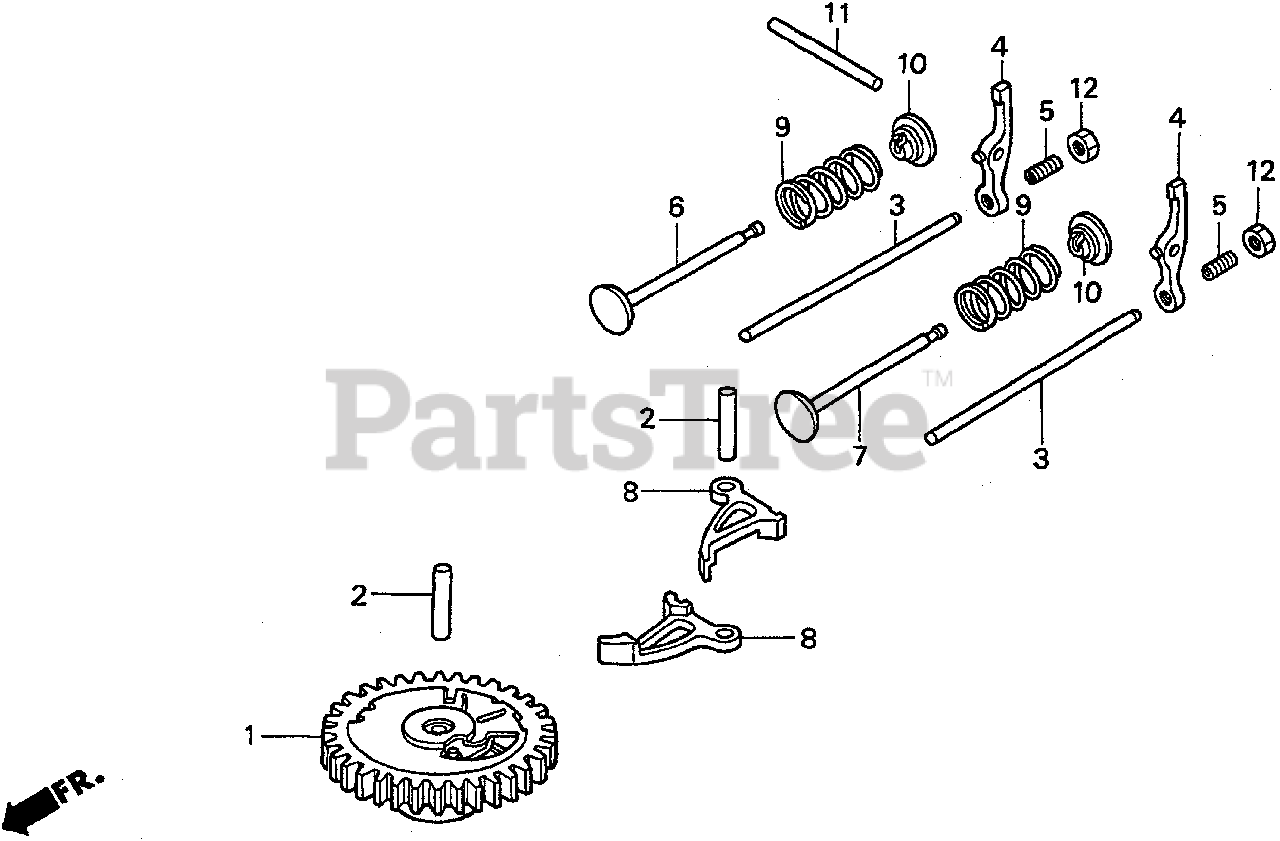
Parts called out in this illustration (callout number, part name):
1	CAMSHAFT ASSY.
2	ROLLER (5X23.8)
3	ROD, PUSH
4	ARM, VALVE ROCKER
5	PIVOT, ROCKER ARM
6	VALVE, IN.
7	VALVE, EX.
8	LIFTER, VALVE
9	SPRING, VALVE
10	RETAINER, VALVE SPRING
11	ROLLER (4X28)
12	NUT, TAPPET ADJUSTING
